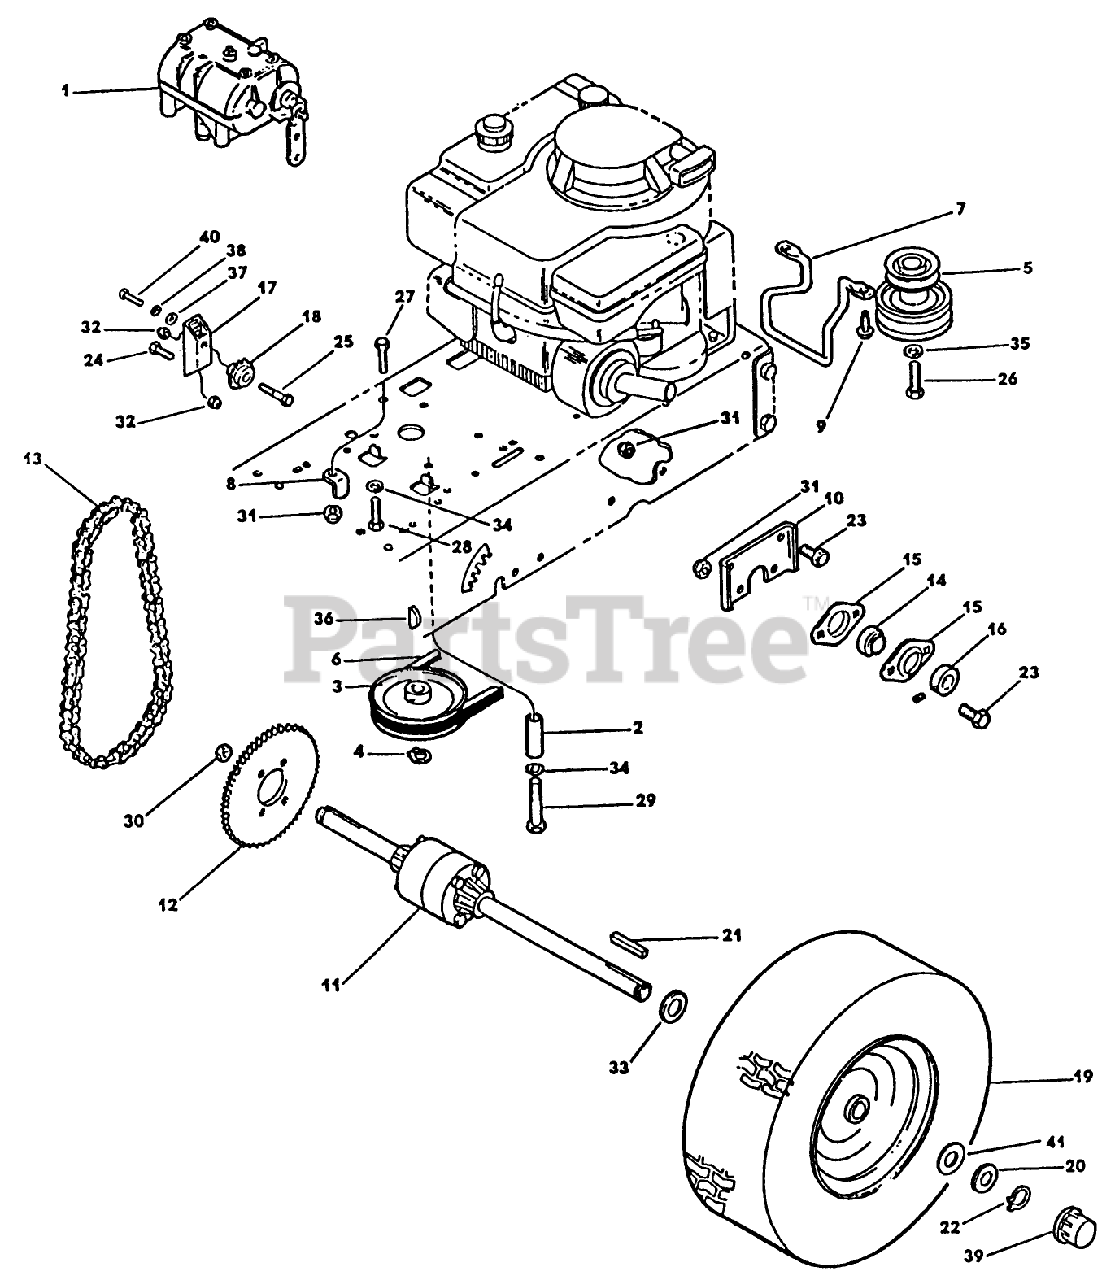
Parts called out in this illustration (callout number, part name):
2	GUIDE - BELT
6	V-BELT S
9	SCREW-THREAD FRMG
12	SPROCKET - RH
14	DISCONTINIUED
15	FLANGETTE-BEARING
16	COLLAR-BEARING
17	IDLER SPRKT BRKT WA*B
20	WASHER
22	RING-RETAINING
23	SCREW - HEX
27	SCREW
31	NUT
32	NUT-LOCKING
38	WASHER
